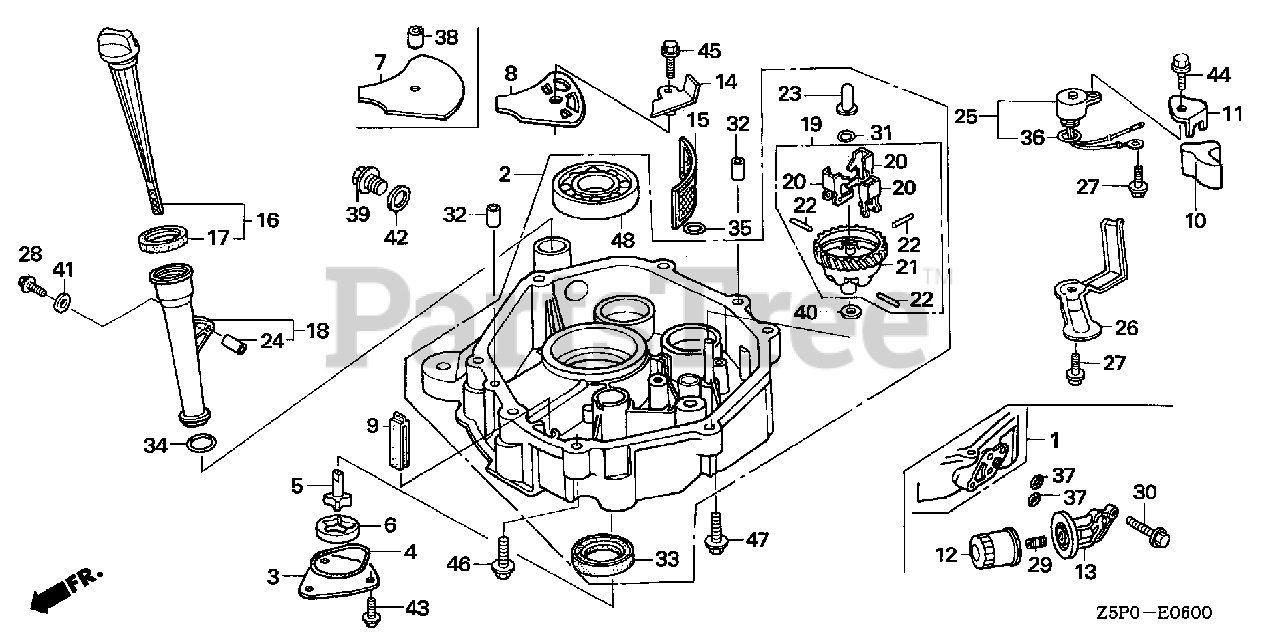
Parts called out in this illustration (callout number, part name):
2	PAN ASSY., OIL
3	COVER, OIL PUMP
4	O-RING, PUMP COVER
5	ROTOR (INNER)
6	ROTOR, OIL PUMP (OUTER)
7	PLATE, OIL FILTER
9	RUBBER, OIL RETURN
15	SCREEN, OIL FILTER
16	CAP ASSY., OIL FILLER
17	GASKET, OIL FILLER CAP
18	EXTENSION, OIL FILLER
19	GOVERNOR ASSY.
20	WEIGHT, GOVERNOR
21	HOLDER, GOVERNOR WEIGHT
22	PIN, GOVERNOR WEIGHT
23	SLIDER, GOVERNOR
24	COLLAR, EXTENSION
28	BOLT, FLANGE (6X35) (CT200)
31	CLIP, GOVERNOR HOLDER
32	PIN, DOWEL (8X12)
33	OIL SEAL (35X52X8)
34	O-RING (22.1X2.2)
35	O-RING (11.8X2.4)
38	COLLAR, OIL FILTER SETTING
39	BOLT, DRAIN PLUG (20MM)
40	WASHER, PLAIN (6MM)
41	WASHER, PLAIN (6MM)
42	WASHER, DRAIN PLUG (20MM)
43	BOLT, FLANGE (6X12)
45	BOLT, FLANGE (6X25)
46	BOLT, FLANGE (8X40)
47	BOLT, FLANGE (8X60)
48	BEARING, RADIAL BALL (6207)
